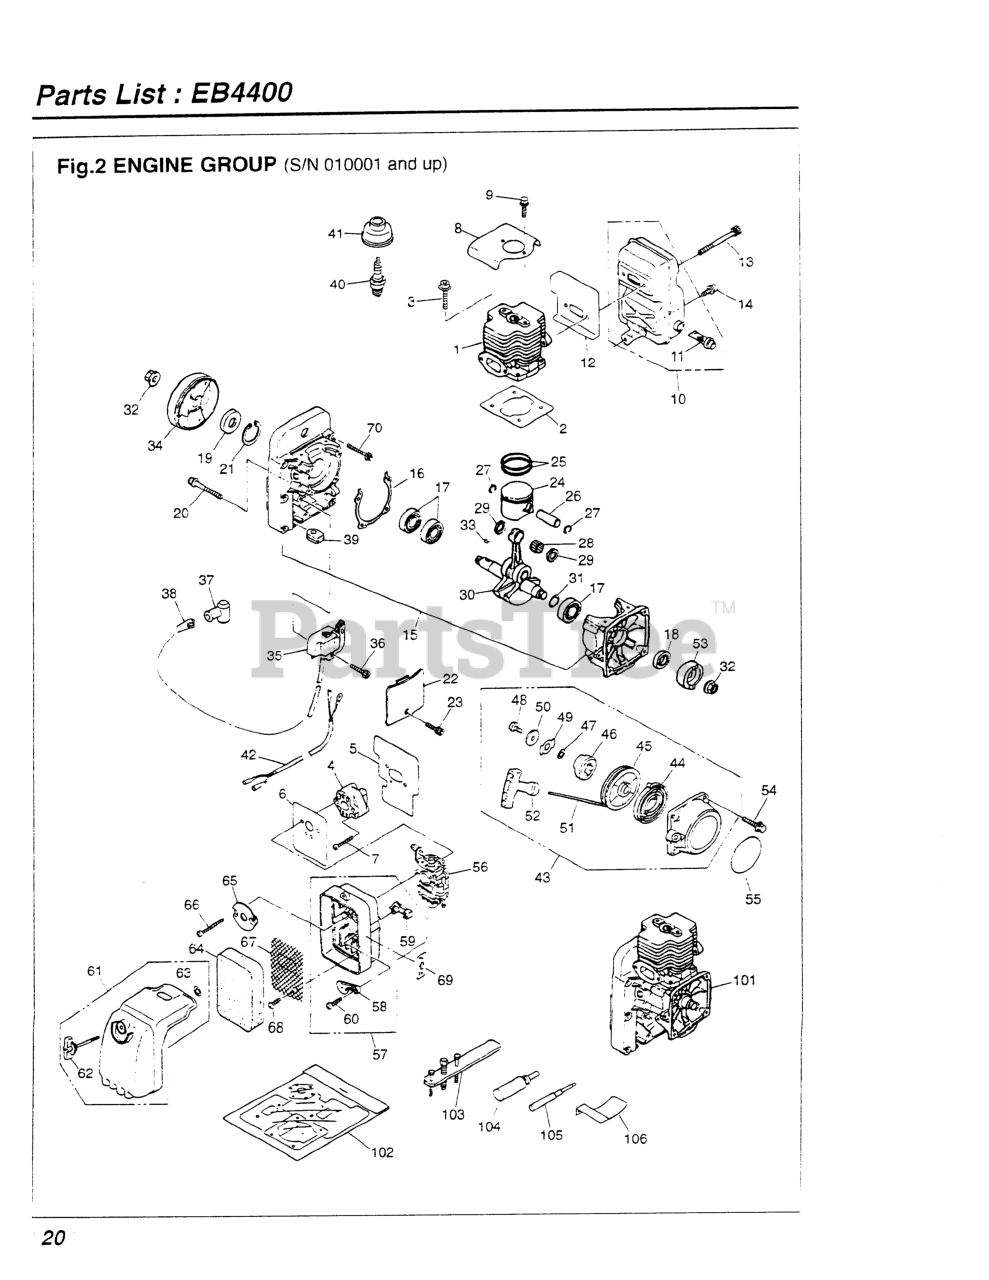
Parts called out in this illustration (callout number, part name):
1	CYLINDER (RPLS -12111)
2	GASKET, BASE
3	BOLT M5 x 20 (RPLS -12280)
5	GASKET
6	GASKET
7	SCREW, M5 x 35
9	BOLT, M5 x 10
10	MUFFLER ASSEMBLY
11	ARRESTER
12	GASKET
13	BOLT, M6 X 70
14	BOLT, M6 X 12
15	CRANKCASE COMPL
16	GASKET
18	SEAL, OIL 15 X 25 X 7
20	BOLT, M5 X 30
21	RING, SNAP, M35 X 1.5
22	COVER
23	BOLT, M4 X 16
24	PISTON (RPLS -41110)
25	RING, PISTON (RPLS -41210)
26	PIN, PISTON (RPLS. 1490-41316)
27	RING, SNAP
28	BEARING
29	WASHER (RPLS 1491-41510)
30	CRANKSHAFT COMPLETE
31	SHIM (REPLACES 848-870-G000)
32	NUT, M10
33	KEY
34	ROTOR (USE 2750-71111)
35	COIL ASSEMBLY, IGINITION
36	BOLT, M4 x 20
37	CAP
38	SPRING
39	GROMMET
41	CAP
42	CORD COMPLETE
44	SPRING (RPLS -75220)
46	DOG
47	WASHER
48	SCREW
49	RETAINER (RPLS 1861-75161)
50	WASHER
51	ROPE
52	KNOB
53	PULLEY (RPLS -75210)
54	BOLT, M5 x 20
56	CARBURETOR
57	BODY, CLEANER
58	PLATE
59	LEVER
60	SCREW (REPLACES 50030272)
61	COVER, CLEANER (RPLS -82200)
62	KNOB
63	RING
64	ELEMENT (RPLS -82310)
65	PLATE (REPLACES -82511)
66	SCREW, M5 x 60
67	SCREEN (RPLS -82351)
68	SCREW
69	LABEL
70	BOLT, M6 X 40
101	BLOCK, SHORT
102	KIT, GASKET
103	PULLER ASSY
104	STOPPER (TOOL) (RPLS 3320-9641
105	GUIDE (TOOL)
